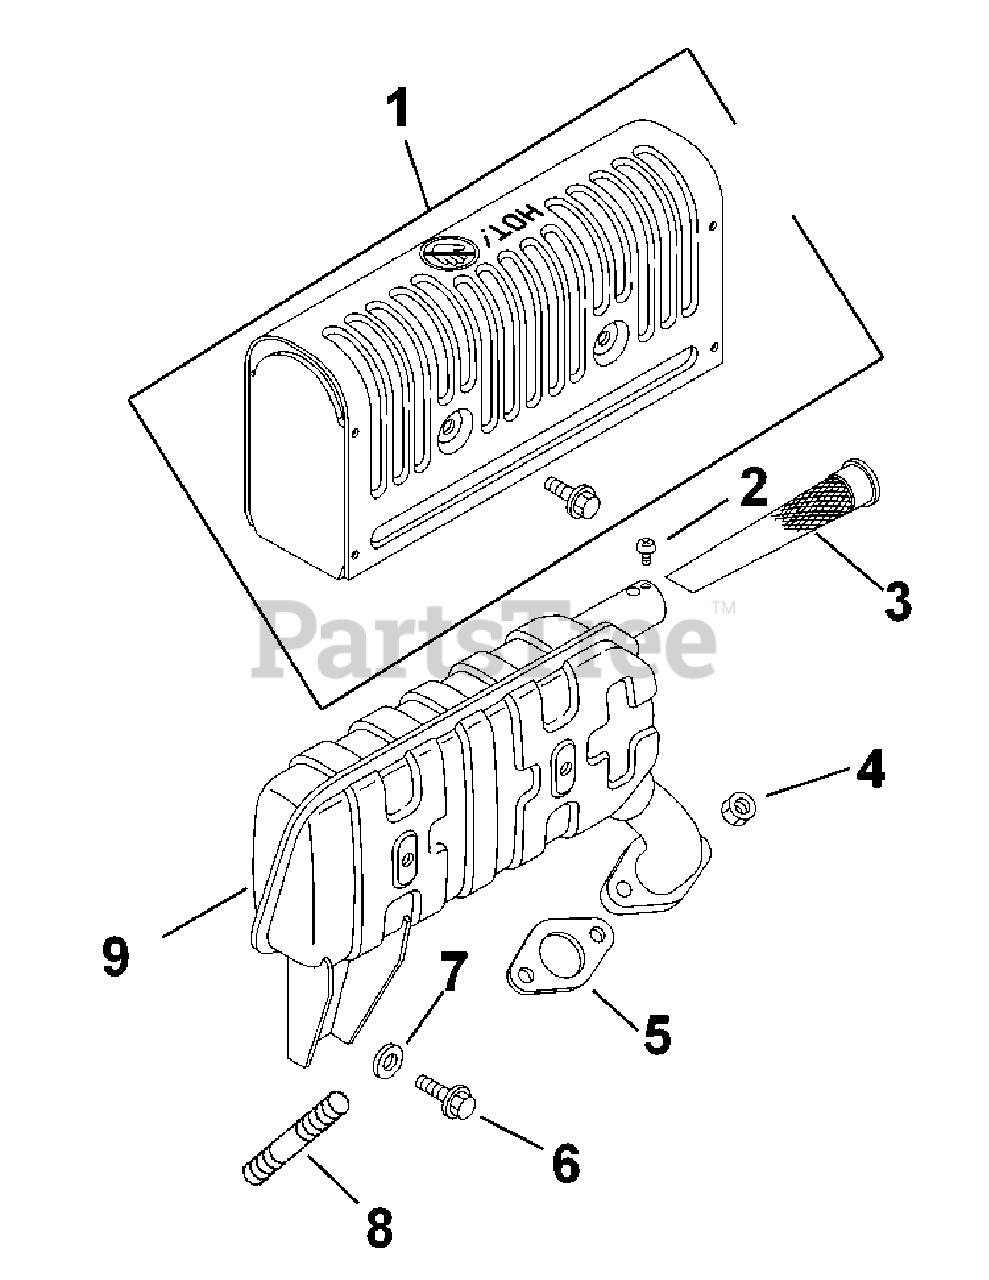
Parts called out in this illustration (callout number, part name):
1	Muffler Guard Kit
3	Spark Arrestor
5	Gasket, Exhaust
6	Screw, Hex Flange
